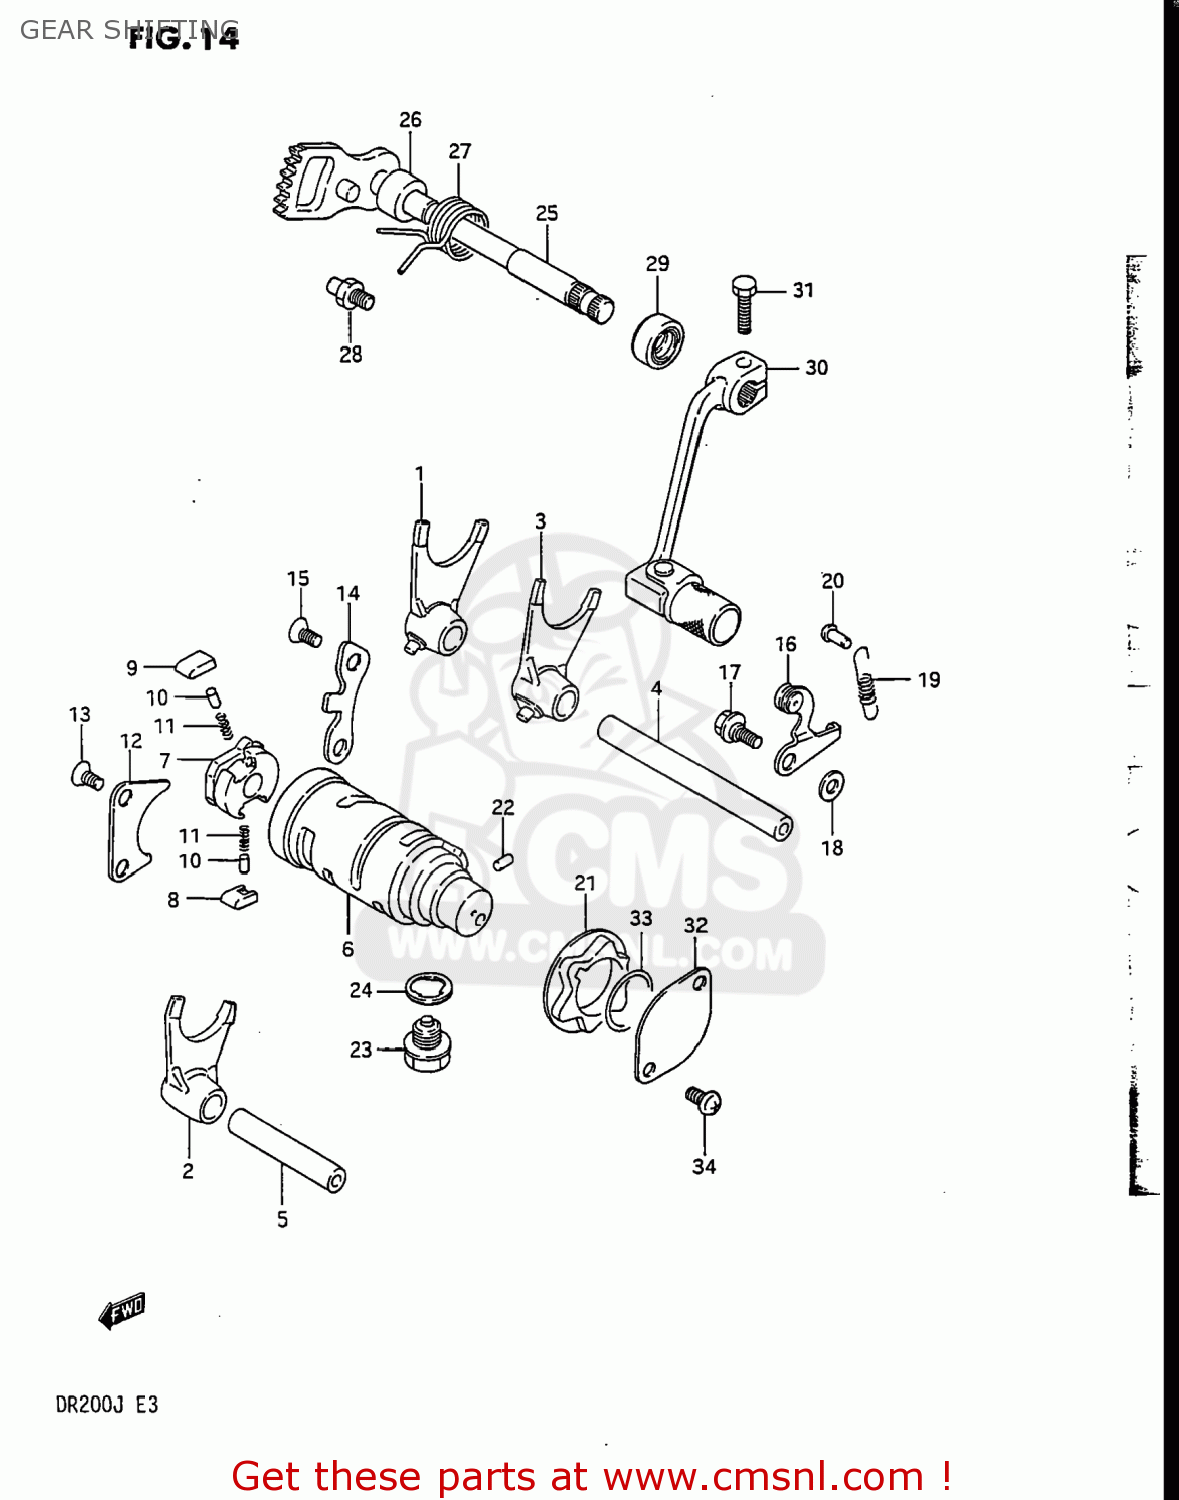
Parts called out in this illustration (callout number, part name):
1	FORK,GEAR SHIFT NO.1
2	FORK,GEAR SHIFT NO.2
3	FORK,GEAR SHIFT NO.3
4	SHAFT,GEAR SHIFT FORK(L:109)
5	SHAFT,GEAR SHIFT FORK
6	CAM,GEAR SHIFT
7	GEAR,GEARSHIFT CAM DRIVE
8	PAWL,GEAR SHIFT NO.1
9	PAWL,GEAR SHIFT NO.2
10	PIN(5X8)
11	SPRING
12	LIFTER,GEAR SHIFT POLE
13	SCREW
14	GUIDE,GEAR SHIFT CAM
15	SCREW
16	STOPPER COMP,GEAR SHIFT
17	BOLT
18	WASHER
19	SPRING
20	RIVET
21	PLATE,GEAR SHIFT CAM STOPPER
22	PIN 4X6
23	PLUG (14X12)
24	GASKET(14X19.2X2) (NAS)
25	SHAFT,GEAR SHIFT
26	SPACER(12X20X15.3)
27	SPRING
28	STOPPER,GEAR SHIFT CAM
29	OIL SEAL
30	LEVER ASSEMBLY,GEAR SHIFTING
31	BOLT
32	CAP,GEAR SHIFT CAM PIVOT
33	O-RING (D:2.4 ID:22.2)
34	SCREW
